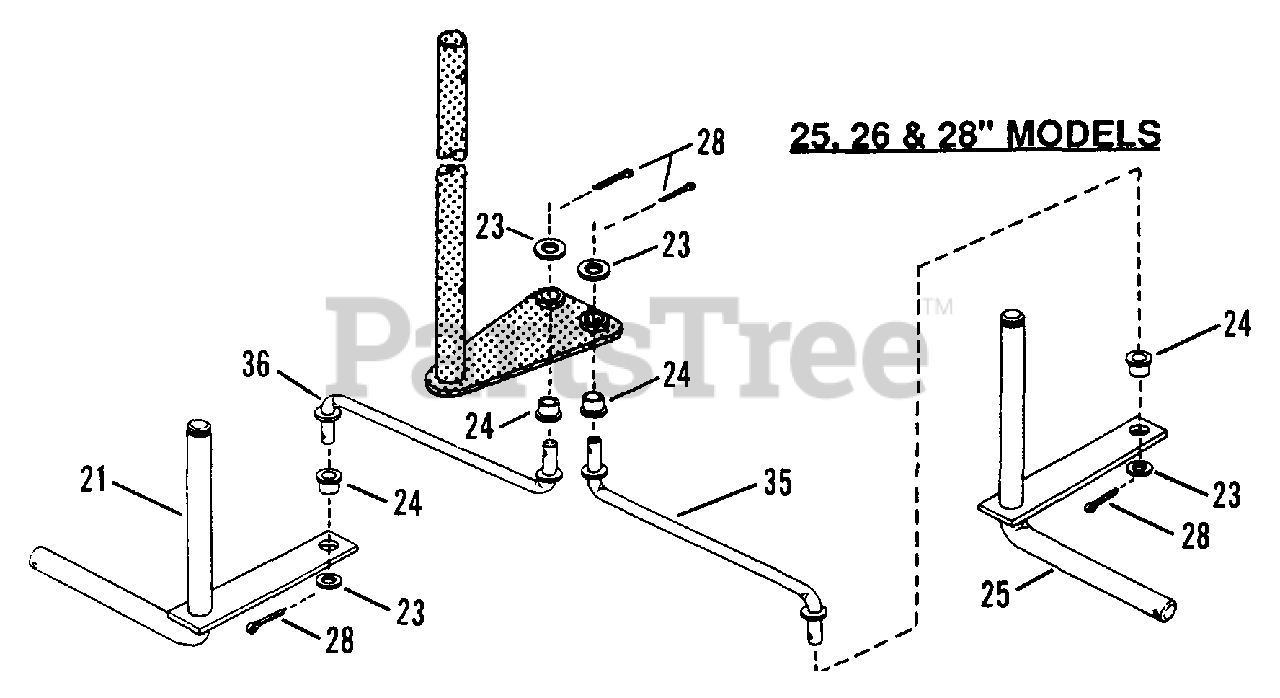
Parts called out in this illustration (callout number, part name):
21	King Pin, R.H.
23	WASHER, 3/8" Flat
24	BUSHING
25	King Pin, L.H.
28	COTTER-PIN, 1/8-3/4"
35	TIE-ROD, Left Side
36	TIE-ROD, Right Side
